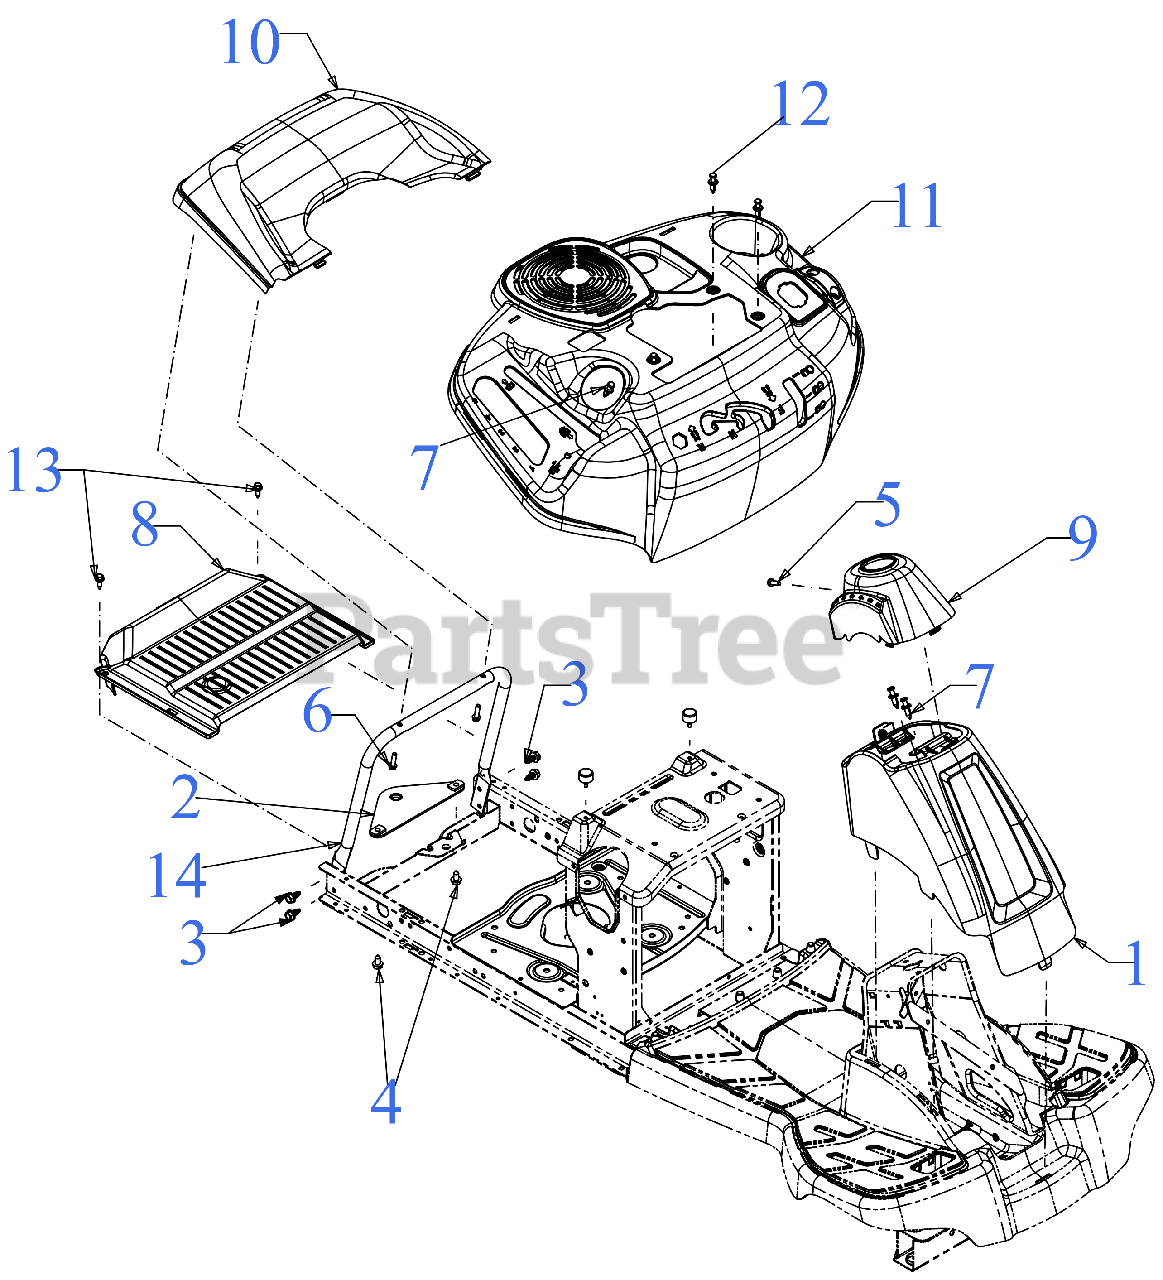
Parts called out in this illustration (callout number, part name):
1	COLUMN COVER (LIBERTY RED)
3	SCREW 5/16-18 x .750
4	SCREW 5/16-18 x .625
5	SCREW 1/4-20X.75
6	SCREW 1/4-15 x 1.00
7	PLASTIC RIVET
8	CVT DRIVE COVER
9	STEERING COLUMN CAP (LIBERTY RED)
10	REAR COVER (LIBERTY RED)
11	FENDER (LIBERTY RED)
12	BUMPER .62 DIA x .50
13	SHOULDER SCREW
